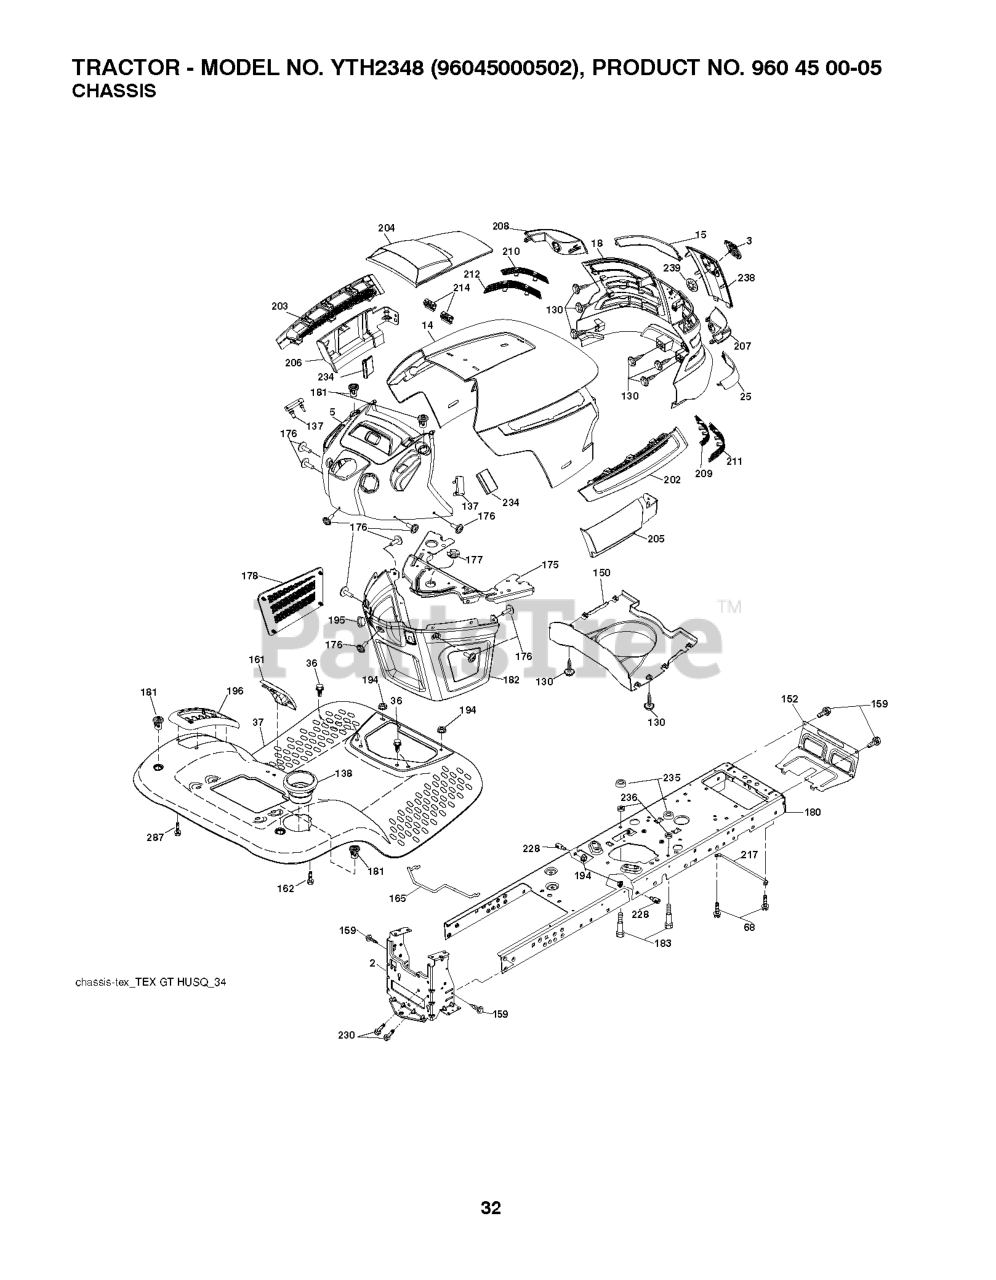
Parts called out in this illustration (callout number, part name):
2	DRAWBAR.1PC.NSTL
3	RP LOGO
5	DASH.ASM.HUSQ.GT.E.RECT.W/CK
7	BOLT.SHOULDER
14	HOOD
15	LENS.LH.TEX.GT.HUSQ.CL
18	GRILL.ASM.HUSQ.TG/CRD.W/TRIM
25	LENS.RH.TEX.GT.HUSQ.CL
36	SCREW 5/16"
37	FENDER.TLT.W/CPH.W/FW.ORANGE
68	Screw 5/16-18 x 1/2 Hex, Self Tapping 5/16-18 x 1/2
130	SCREW.#10 X 0.750.BOS
137	BUMPER DASH
138	CUPHOLDER.TL.TEX.418
150	AIR.DUCT.HOOD.TEX.GT.HUSQ
152	SHIELD.BROWNING/DEBRIS
159	SCREW, 3/8-16X3/4
161	WINDOW FUEL
162	SCREW.HI-LO.CONSOLE
165	SUPPORT.TANK.REAR.B/TE
175	PLATE.CROSSMEMBER.HUSQ
176	SCREW.#10-24X5/8.RN.QU
177	BUSHING, STEERING
178	CARGO.ASM.NET.TXGT.W/C
180	CHASSIS.STAMPING.LT/GT
181	BUSHING.MNT.FEND.CRGO.
182	DASH.LOWER.COMMON.12V.ADAPTOR
183	BOLT.5/16-18X1-1/4 FULL.THREAD
194	NUT LOCK HEX FLANGE 5/16-18
195	PLUG.HOLE.DASH.LOWER.12V.BLK
196	RP CONSOLE.ASM.DECKLFT.GR/RBT.
202	VENT.SIDE.HOOD.HUSQ.RH.GREY
203	VENT.SIDE.HOOD.HUSQ.LH.GRAY
204	HOOD VENT
205	SKIRT.HOOD.SIDE.HUSQ.RH.GREY
206	SKIRT.HOOD.SIDE.HUSQ.LH.GREY
207	BEZEL.RH.TEX.GT.HUSQ
208	BEZEL.LH.TEX.GT.HUSQ
209	INSERT.HEX.GRILL.HUSQ.GREY
210	INSERT.HEX.GRILL.HUSQ.
211	INSERT.HEX.GRILL.HUSQ.
212	INSERT.HEX.GRILL.HUSQ.
214	CLIP.RETAINER.TINNER.
217	ROD.PIVOT.HOOD
228	STUD.FASTNER.W/ANTI-ROTATE
230	BOLT.SHOULDER
234	BUMPER.HOOD.TEX.HUSQVARNA
235	SPACER FENDER
236	NUT.CENTERLOCK.5/16-
238	TRIM.HUSQ.TG/CRD.SERVICE
239	NUT PUSH M
287	SCREW 1/4X20
